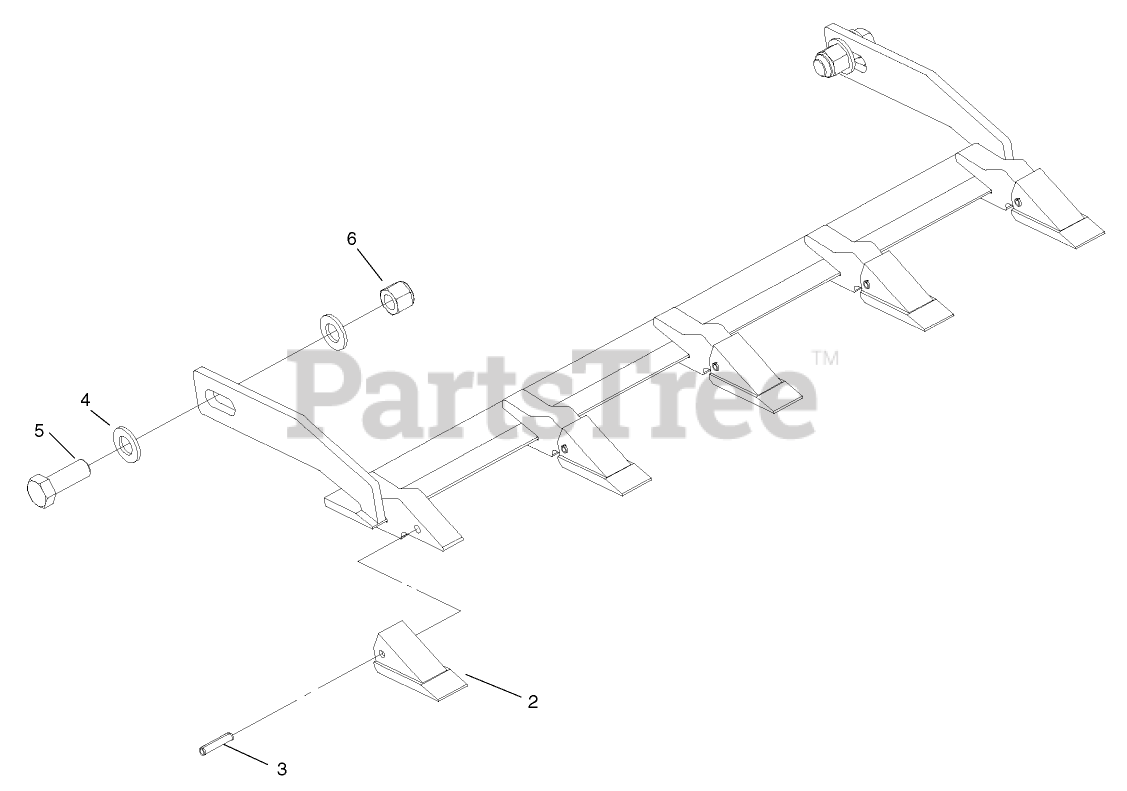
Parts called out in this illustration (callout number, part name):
2	TOOTH-BUCKET
3	PIN-ROLL
4	WASHER-FLAT
5	SCREW-HH
6	NUT-LOCK, NI
